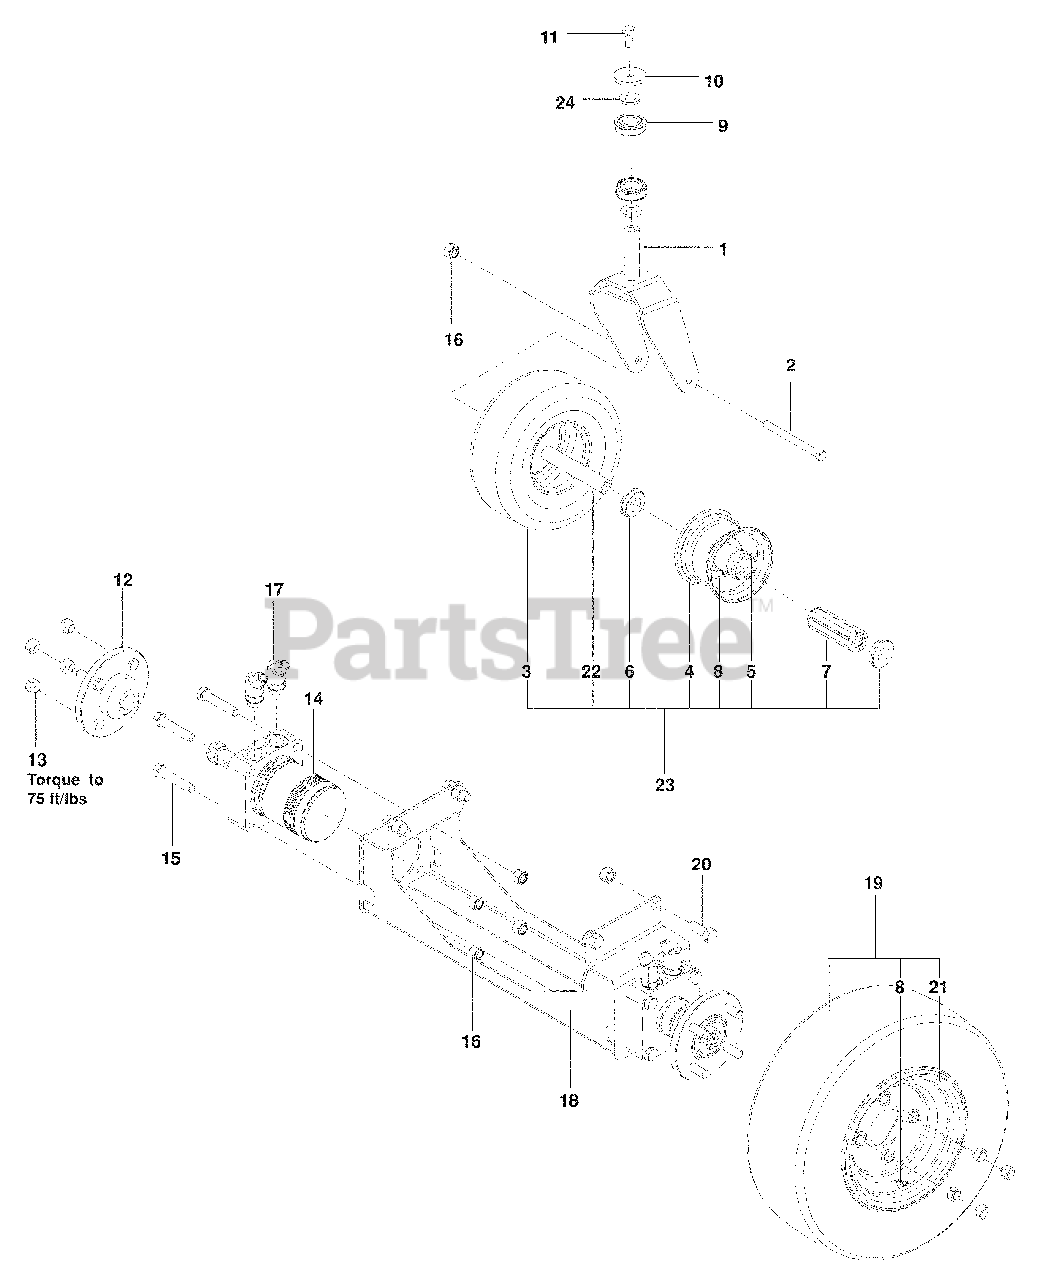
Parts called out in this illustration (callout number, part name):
1	CASTER FORK
2	HCS ½-13 x 5½
3	TIRE, CASTER
4	RIM, CASTER
5	ZERK
6	BEARING, FLANGE
7	ROLLER BEARING
10	WASHER, HEAVY
11	HCS ½-13 x 1
12	HUB, WHEEL
13	NUT, LUG ½
15	HCS ½-13 x 2½
16	NUT ½ HEX NYLOC
17	ELBOW 45° STRAIGHT THD
18	AXLE FRAME
19	WHEEL ASSY, REAR WHF3617
20	HCS ½-13 x 1¼
21	RIM WHF3617
23	WHEEL ASSY, CASTER
